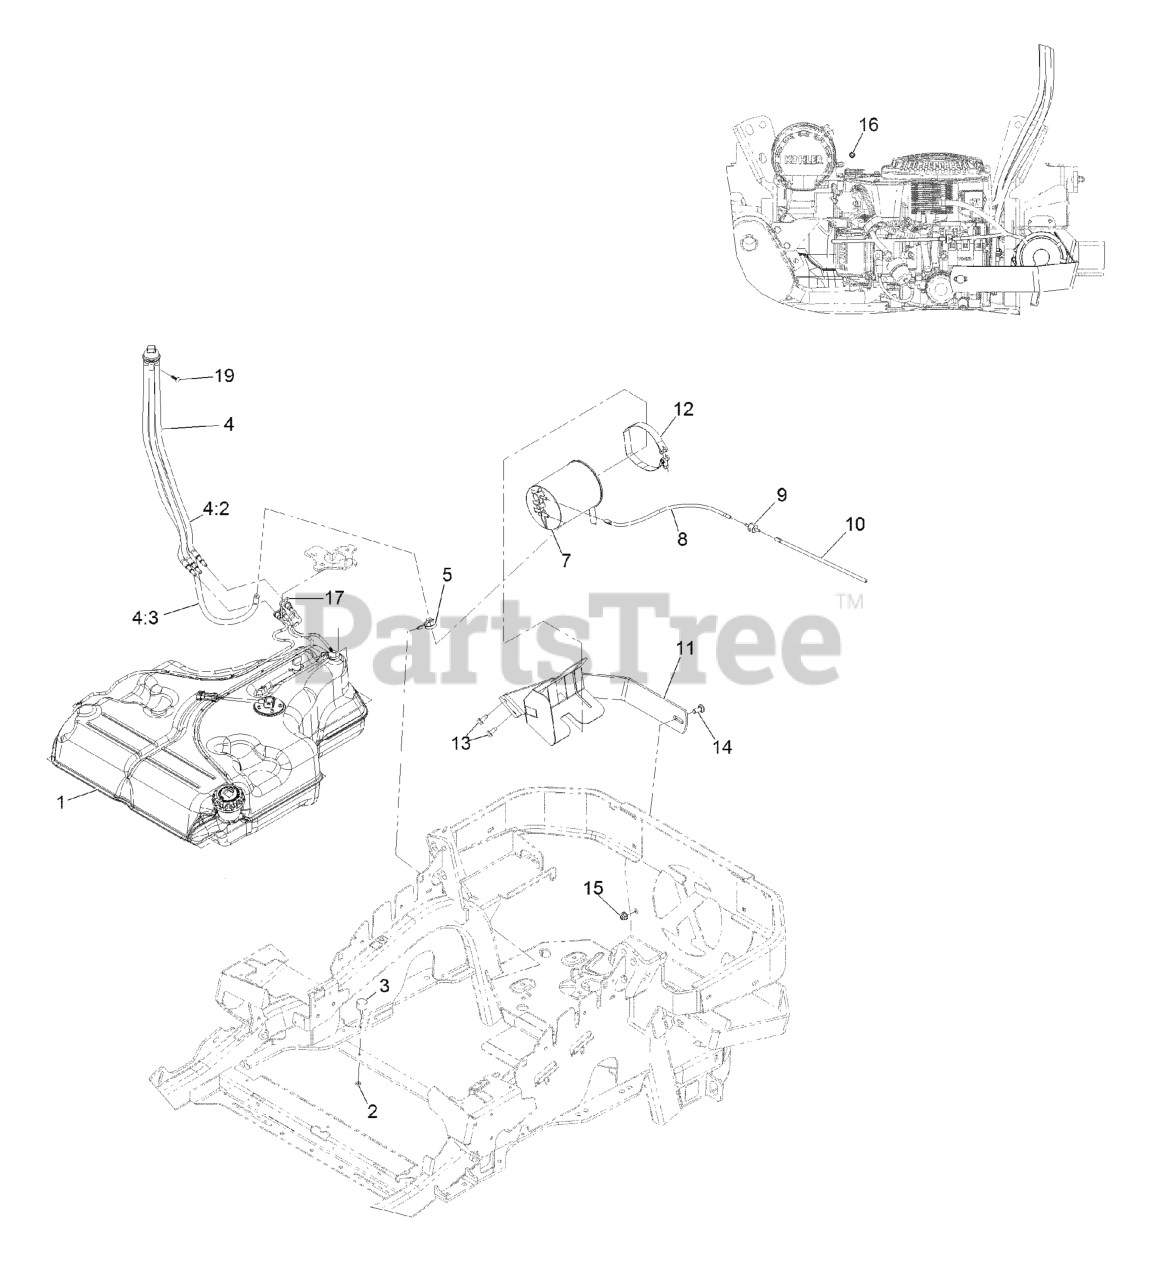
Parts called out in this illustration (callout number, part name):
2	NUT-JAM
4	FUEL MANIFOLD VENT ASM
4:2	HOSE-FUEL
4:3	HOSE-FUEL
5	CLAMP-HOSE
7	CANISTER-CARBON, 1200CC
8	HOSE-VENT, FORMED
9	VALVE-CONTROL, VACUUM
10	HOSE-VENT, FORMED
11	MOUNT-CANISTER
12	CLAMP, T-BOLT
13	Screw-HWH 5/16-18 X 3/4 Tf
14	SCREW-CARR
15	NUT-HF, NI
16	TIE-PLASTIC
17	HOSE-VENT, FORMED
18	PLUG-PORT
19	RETAINER-LINE, VAPOR
21	PLUG-PLASTIC
